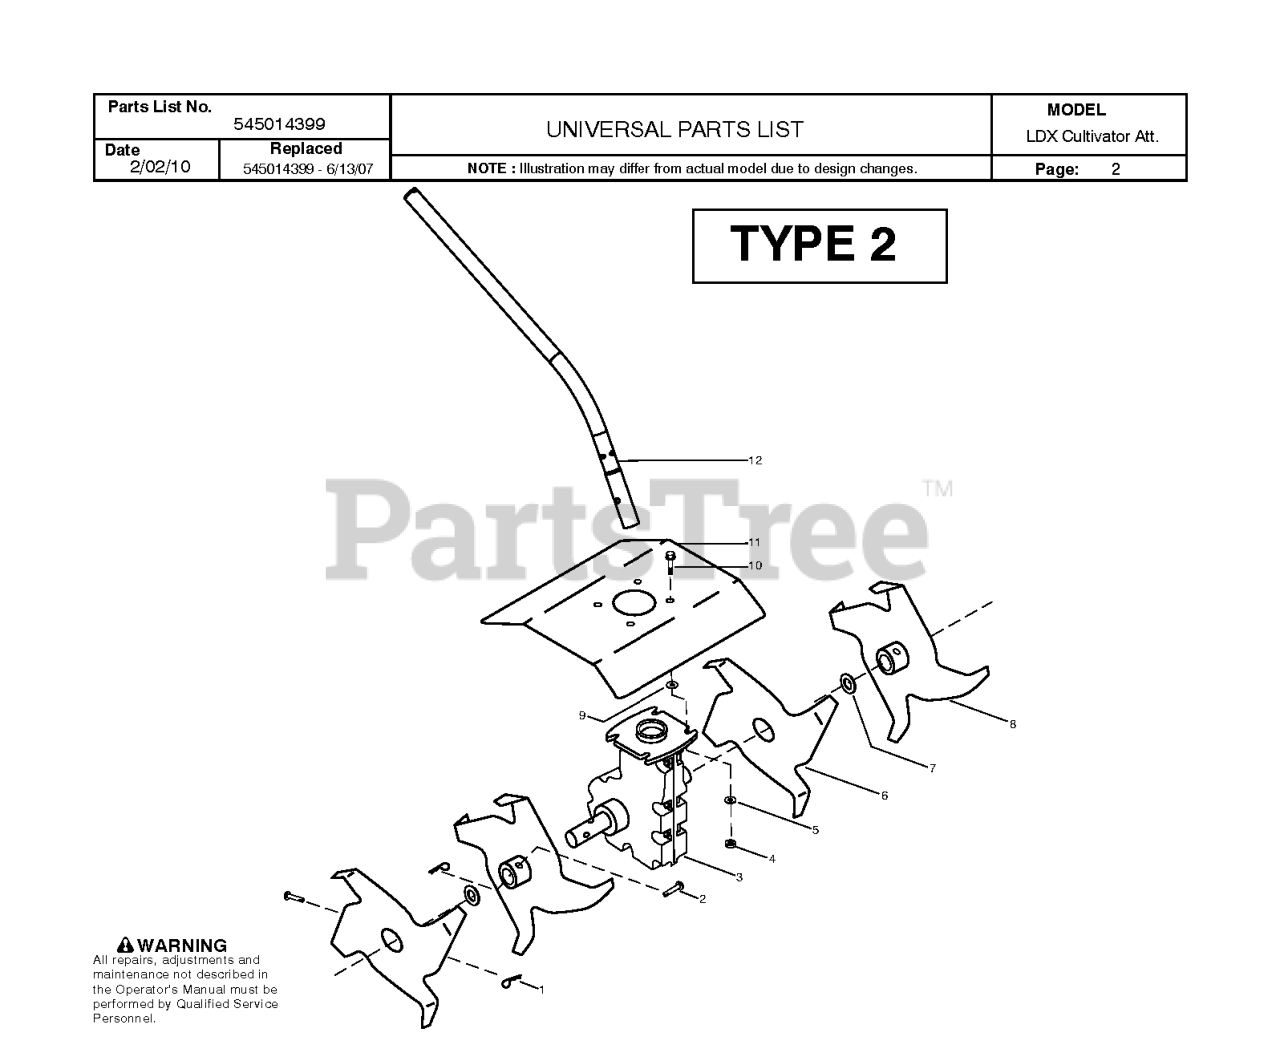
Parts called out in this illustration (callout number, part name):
1	RETAINER,HAIRPIN
2	PIN,CLEVIS
3	GEAR ASSY GEARBOX
5	WASHER,FLAT
6	TINE,RIGHT OUTSIDE/LEFT INSIDE
7	WASHER,FELT
8	TINE,LEFT OUTSIDE/RIGHT INSIDE
9	WASHER,FLAT
10	BOLT,WASHER HEAD
12	SHAFT
